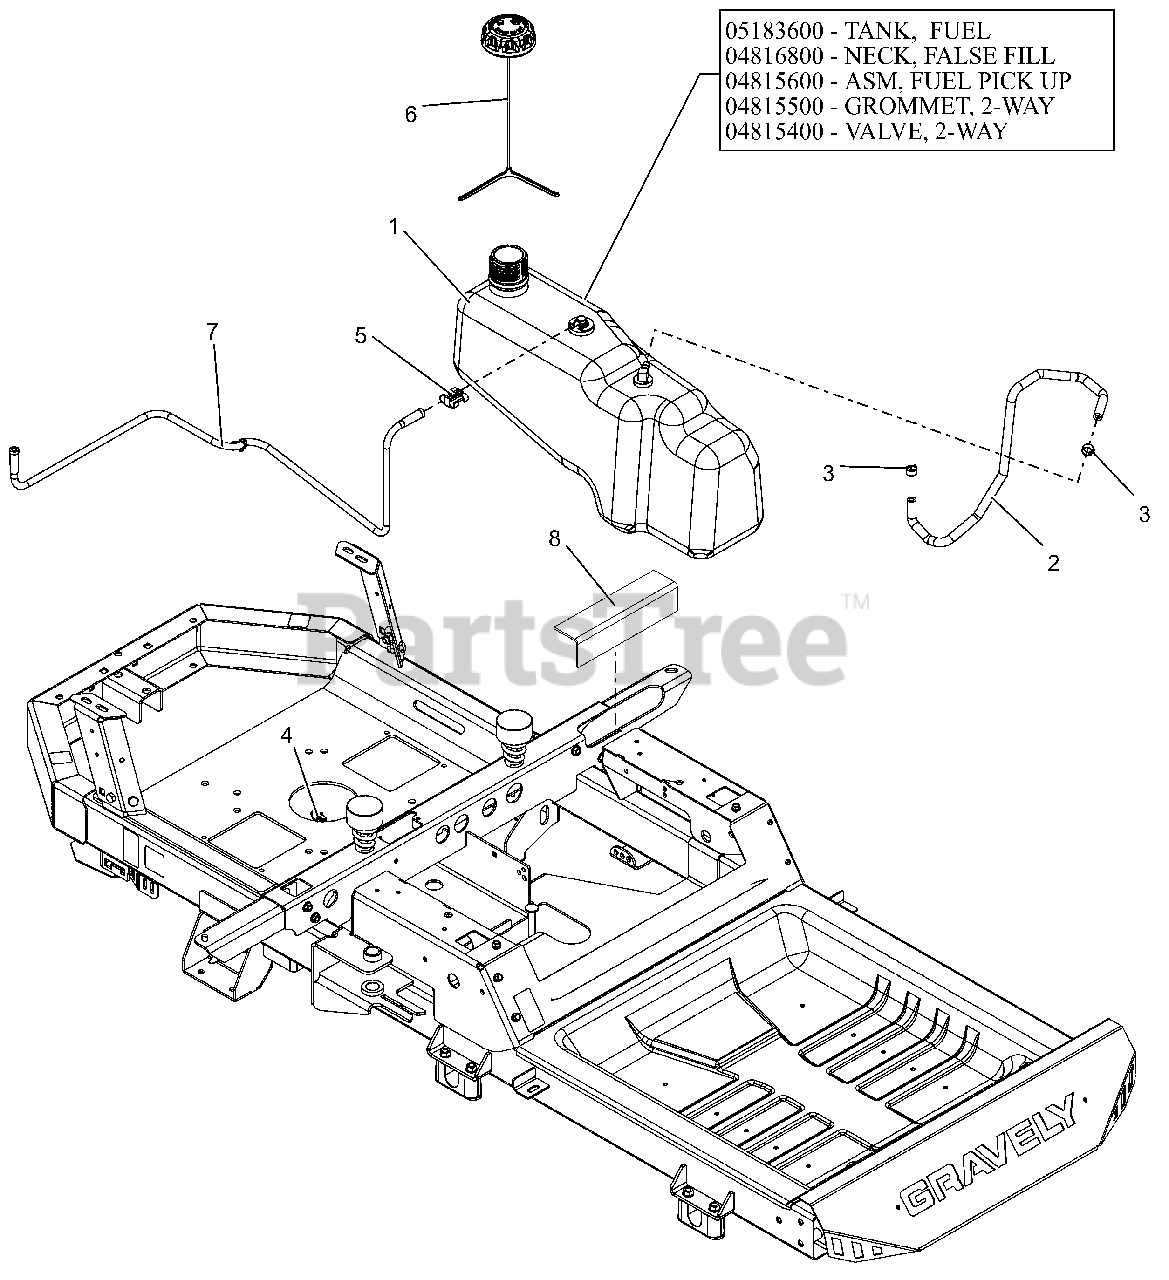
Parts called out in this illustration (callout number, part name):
1	ASM, FUEL TANK - ZTX
1	TANK, FUEL-ZTX
1	NECK, FALSE FILL ZOOM/ZT
1	ASM, FUEL PICK-UP ZOOM/ZT 2015
1	GROMMET, 2-WAY
1	VALVE, 2-WAY
2	HOSE, .25 LOW-PERM BULK GAS
3	CLAMP, FUEL LINE
4	ROUTING CLIP (1/2" ID)
5	CLIP, T, .38-.50
6	CAP, FUEL VENT-IN 2.25" RATCH.
7	LINE, FUEL VENT KOHLER SMCHOKE
8	PAD, RUBBER-TANK
